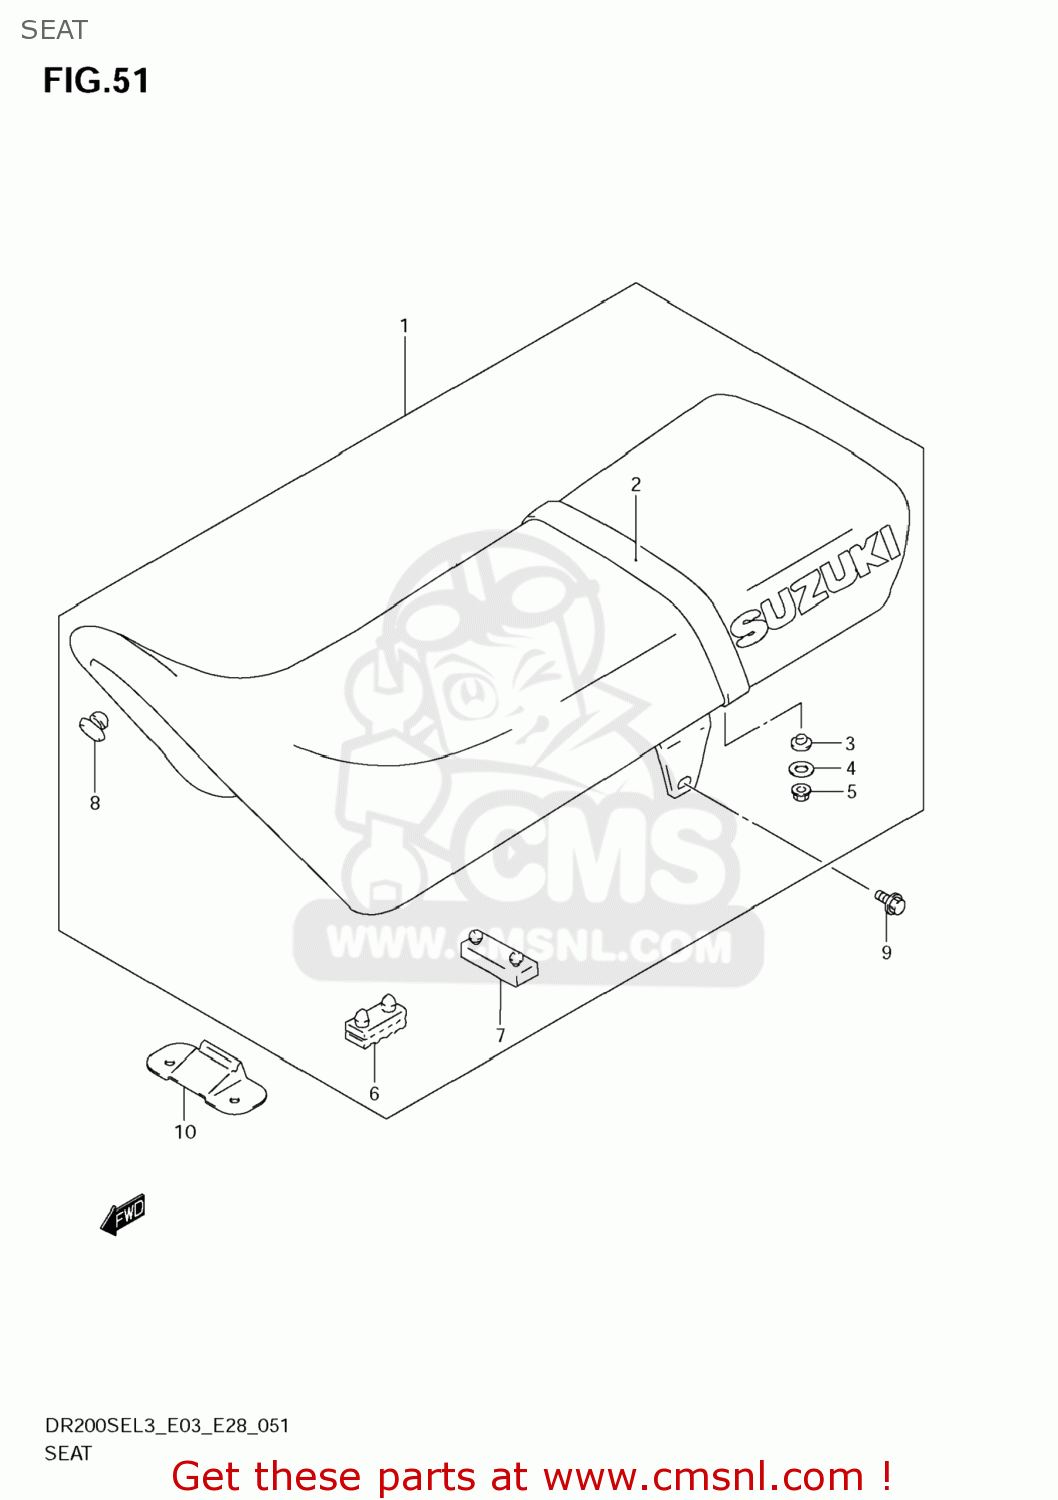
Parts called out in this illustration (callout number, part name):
1	SEAT ASSY
2	BAND,SEAT(BLACK)
3	WASHER
4	WASHER
5	NUT
6	CUSHION,SEAT(40X20X15)
7	CUSHION,SEAT
8	CUSHION
9	BOLT
10	PLATE,SEAT FR HOOK
